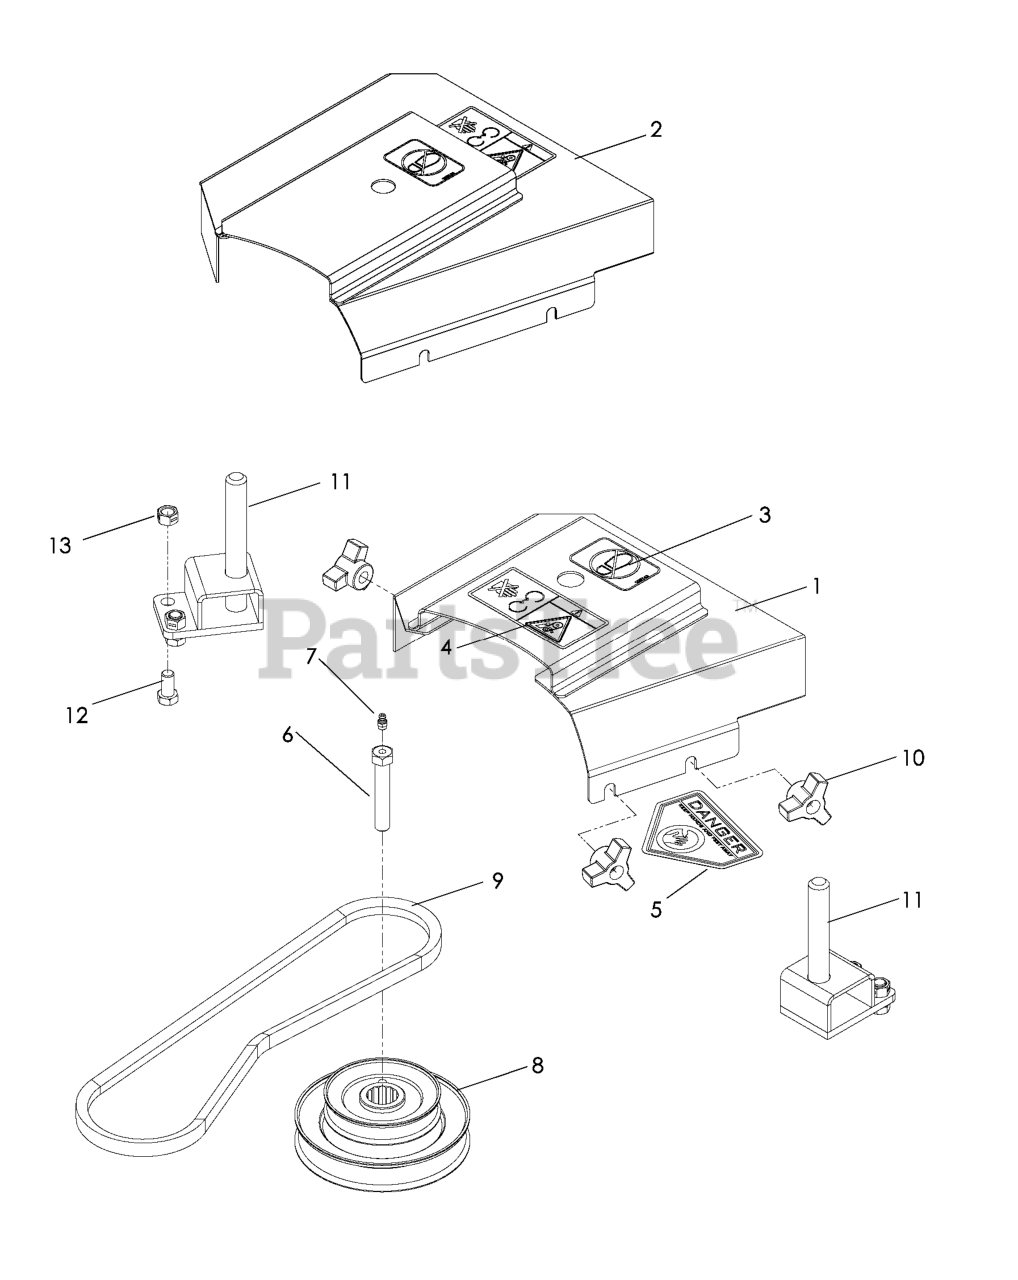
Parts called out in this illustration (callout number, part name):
1	BELT SHIELD W/DECALS, 52
2	BELT SHIELD W/DECALS, 61
3	DECAL, NO STEP
4	DECAL, BELT DRIVE
5	DECAL, CPSC
6	HCS, 7/16-20 X 2 1/2, GR8
7	ZERK
9	61 DBL HEX HEAD STACKED PULLEY
10	V-BELT PUMP DRIVE
11	V-BELT 61" SPINDLE DRIVE
12	KNOB, THREE PRONG
13	BLOWER PIN WELDMENT ASM.
14	SCREW 3/8C X 3/4 HEX CAP
15	NUT 3/8C CENTERBLOCK
